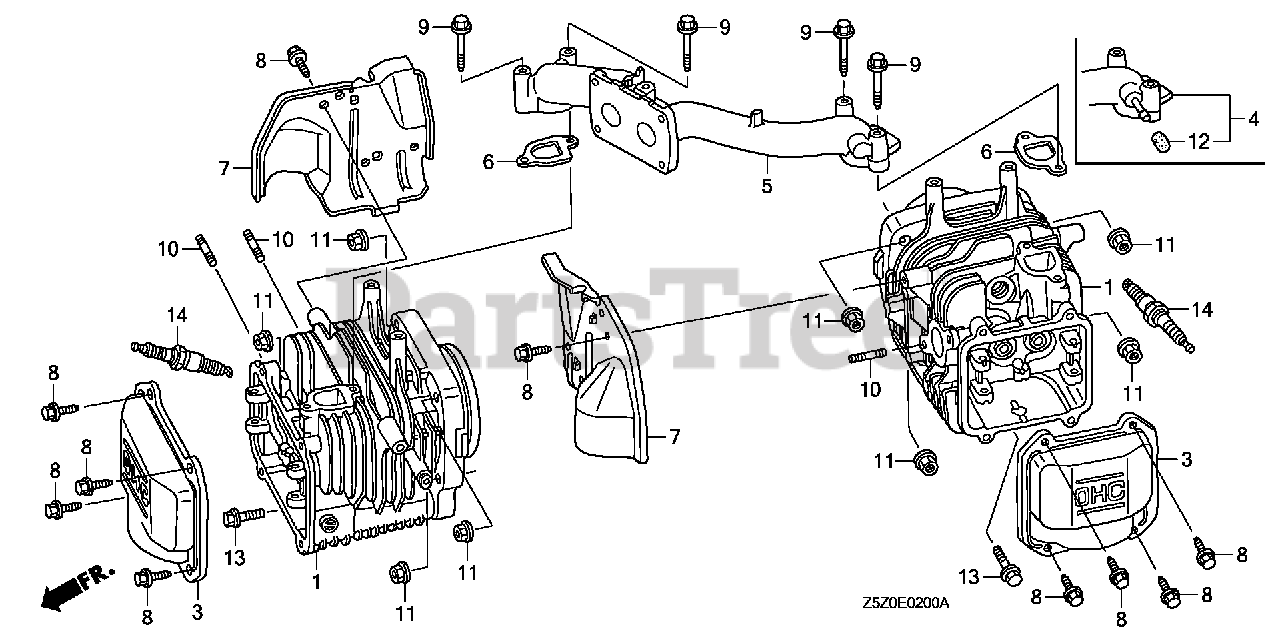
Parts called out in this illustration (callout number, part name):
1	CYLINDER
3	COVER, HEAD
5	MANIFOLD, IN.
6	GASKET, IN. MANIFOLD
8	BOLT, FLANGE (6X12) (CT200)
9	BOLT, FLANGE (6X45) (CT200)
10	BOLT, STUD (6X28) (CT200)
11	NUT, FLANGE (8MM)
13	BOLT, FLANGE (6X30)
14	SPARK PLUG (BPR4ES) (NGK)
14	SPARK PLUG (W14EPR-U) (DENSO)
14	SPARK PLUG (BPR5ES) (NGK)
14	SPARK PLUG (W16EPR-U) (DENSO)
